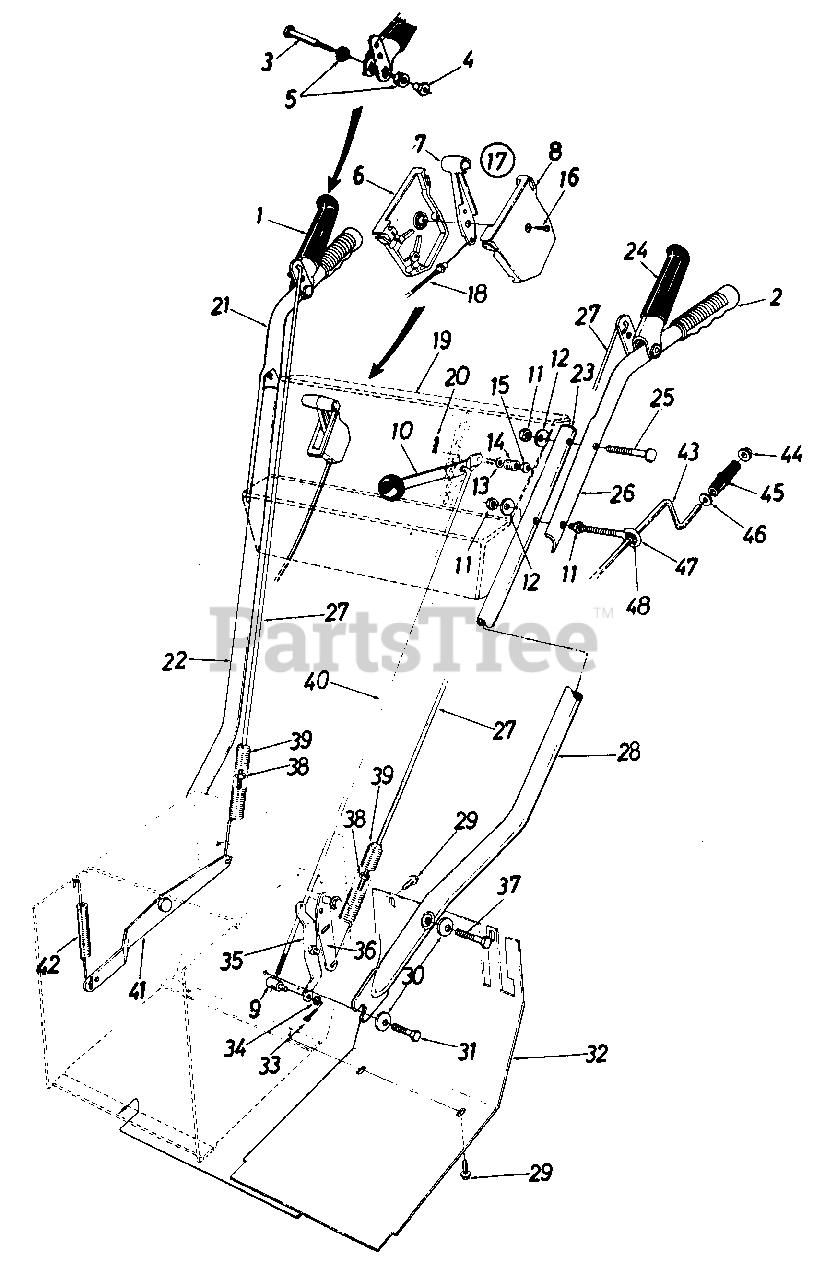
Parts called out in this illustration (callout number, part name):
1	Clutch Grip Ass'y .-R.H.
2	Grip
3	Shoulder Bolt .374 Dia. x 1.53" Lg.
4	Shld. Nut 1/4-20 Thd.
5	Hex Flange Plastic Bearing .38" I.D.
9	Adjustment Ferrule
10	Shift Handle Ass'y.
11	Hex Nut 5/16-18 Thd.*
12	Bell-Wash. .34" I.D. x .88" O.D.
13	Bell-Wash. .40" I.D. x .88" O.D.
14	Compression Spring
15	Hex Ins. L-Nut 3/8-24 Thd.
17	Throttle Control Box Ass'y.
18	Throttle Control Wire
19	Handle Panel Ass'y.
20	Int. Cotter Pin 5/16" Dia.
21	Upper Handle-R.H.
22	Lower Handle-R.H.
23	Plastic Plug
24	Clutch Grip Ass'y.-L.H.
25	Carriage Bolt 5/16-18 x 2.0" Lg.
26	Upper Handle-L.H.
27	Lockout Rod
28	Lower Handle-L.H.
29	Hex Wash. Hd. Self-Tap Scr. 5116-24 x .50" Lg.
30	Bell-Wash. .40" I.D. x .88" O.D.
31	Pilot Hex Scr. 3/8-16 x .88" Lg.
32	Frame Cover
33	Cotter Pin 3/32" Dia.*
34	Fl-Wash. .345 I.D. x .62 O.D. x .06
35	Shifting Linkage Brkt.
36	Drive Clutch Brkt. Ass'y.
37	Hex Bolt 3/8-16 x 2.0" Lg.*
38	Hex Ins. L-Nut 1/4-20 Thd.
39	Ext. Spring .75" O.D. x 5" Lg.
40	Shift Rod
41	Auger Clutch Brkt.
42	Ext. Spring .38" O.D. x 3.18" Lg.
43	Chute Crank Ass'y.
44	Push Nut 318" Rod
45	Knob 3/8" Rod
46	Fl-Wash. .40" I.D. x .62" O.D.
47	Eyebolt 5/16-18 x 5.0" Lg.
48	Grommet
